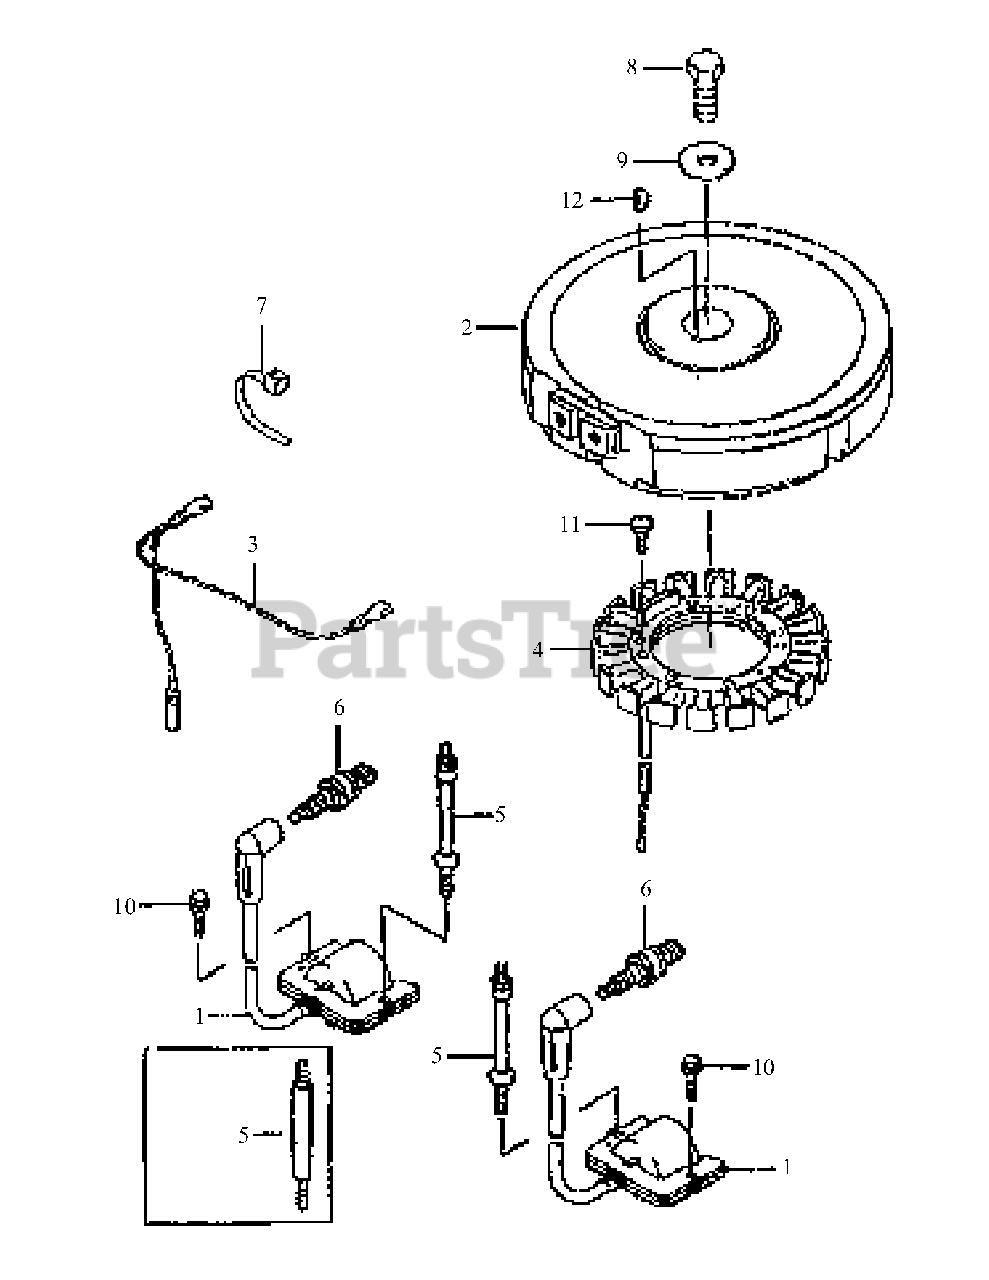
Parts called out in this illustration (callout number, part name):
1	Coil, Ignition
4	Coil, Charging
5	Stud
6	Spark Plug
10	Bolt, Flange
11	Screw
12	Key, Woodruff
